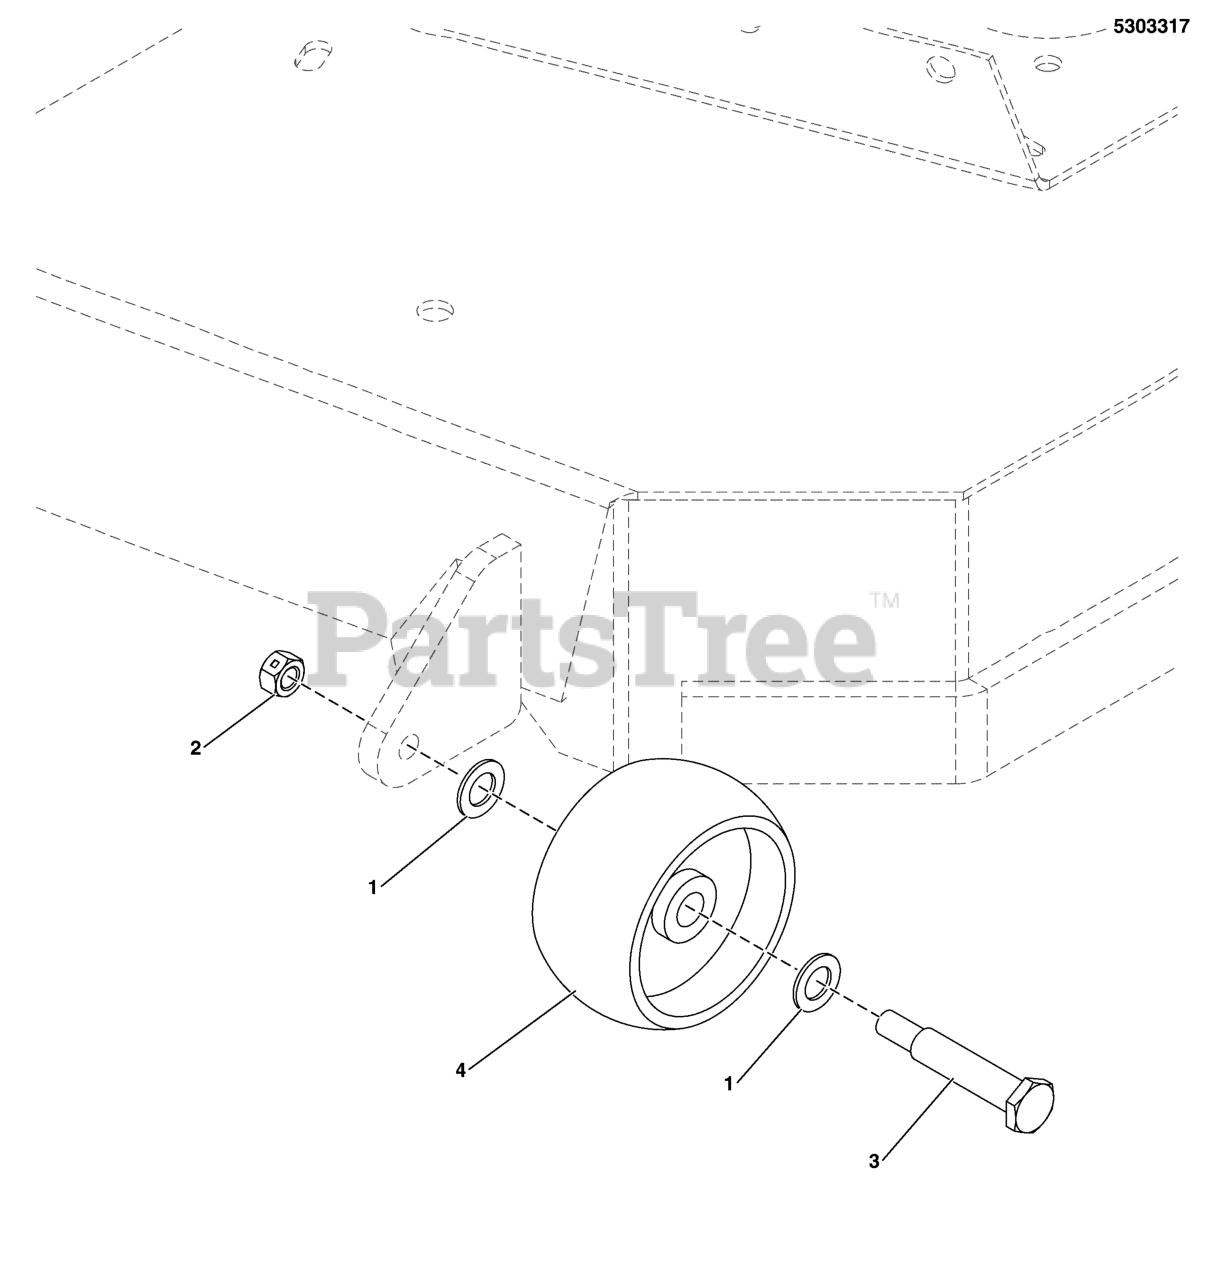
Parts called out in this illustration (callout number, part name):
1	WASHER,.516IDX.875ODX.06,FLAT,ZC/CL
2	NUT, 3/8-16 HEX SIDE LOCK
3	BOLT, REAR WHEEL
4	WHEEL- 2.00 WIDE 3.88 DIA 0.531ID POLY
